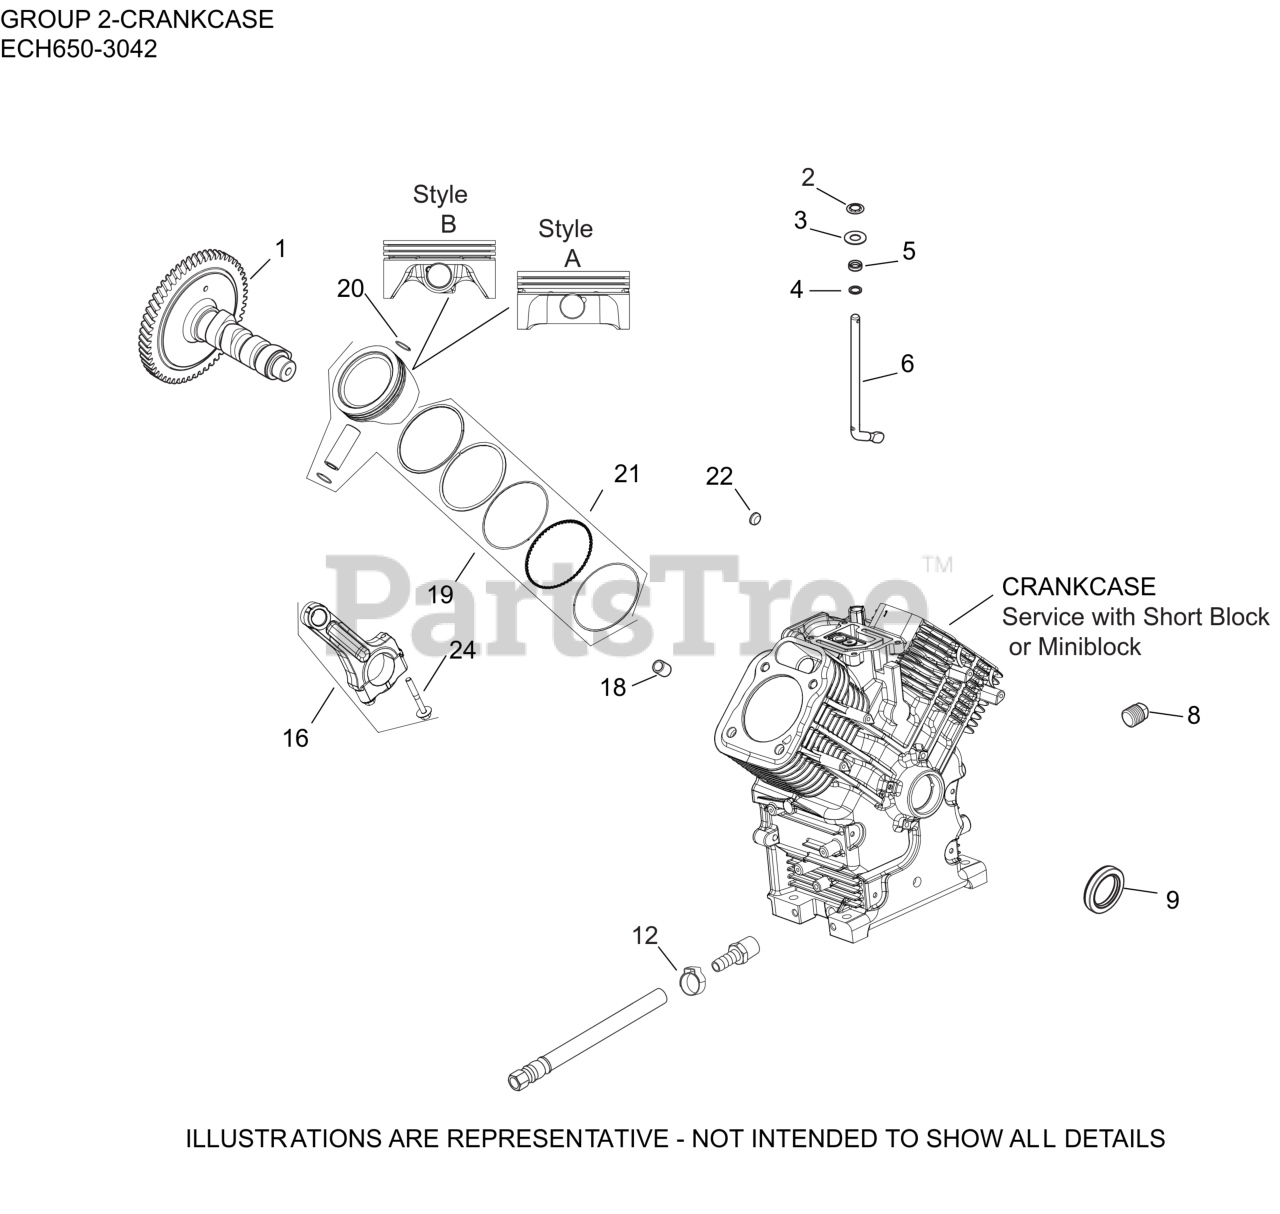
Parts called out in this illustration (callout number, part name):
1	KIT, CAMSHAFT
2	RETAINER, RING
3	WASHER, FLAT 9 MM
4	WASHER, FLAT 11/32"
5	SEAL, GOVERNOR CROSS SHAFT
6	SHAFT, GOVERNOR CROSS
8	PLUG, HD PIPE 3/8"
9	SEAL, OIL (HELIX LIP)
16	ROD, ASSEMBLY CONNECTING
18	PIN, LOCATING
19	KIT, PISTON (STD) STYLE B
19	KIT, PISTON (.08) STYLE B
19	KIT, PISTON (.25) STYLE B
19	KIT, PISTON (.50) STYLE B
20	RETAINER, PISTON PIN
21	RING SET (STD) STYLE B
21	RING SET (.08) STYLE B
21	RING SET (.25) STYLE B
21	RING SET (.50) STYLE B
22	PLUG, CUP
24	KIT, ROD BOLTS-(#25086677S)
